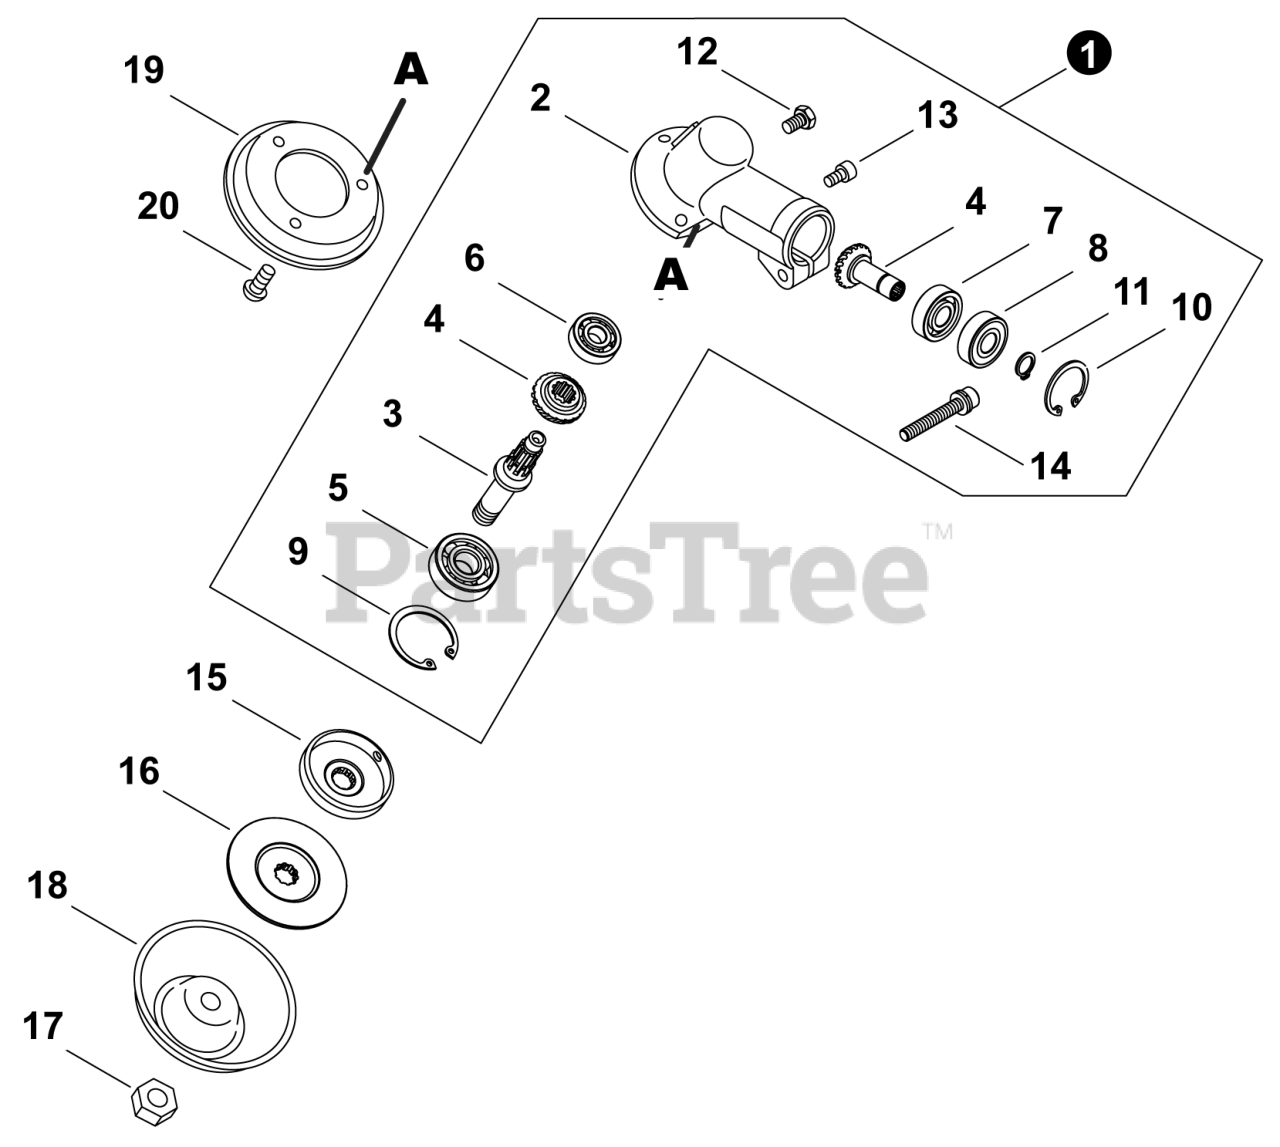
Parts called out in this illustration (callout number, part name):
1	GEAR CASE ASSY
2	CASE, GEAR
3	SHAFT, GEAR
4	GEAR SET, BEVEL
5	BEARING, BALL
6	BEARING, BALL
7	BEARING, BALL
8	BEARING, BALL
9	RING, SNAP
10	RING, SNAP
11	RING, SNAP
15	PLATE, ADAPTOR - UPPER
16	PLATE, ADAPTOR - LOWER
17	NUT, LOCK 10 - NYLON INSERT
18	ADAPTER, SAW
19	RETAINER, LOWER BLADE
